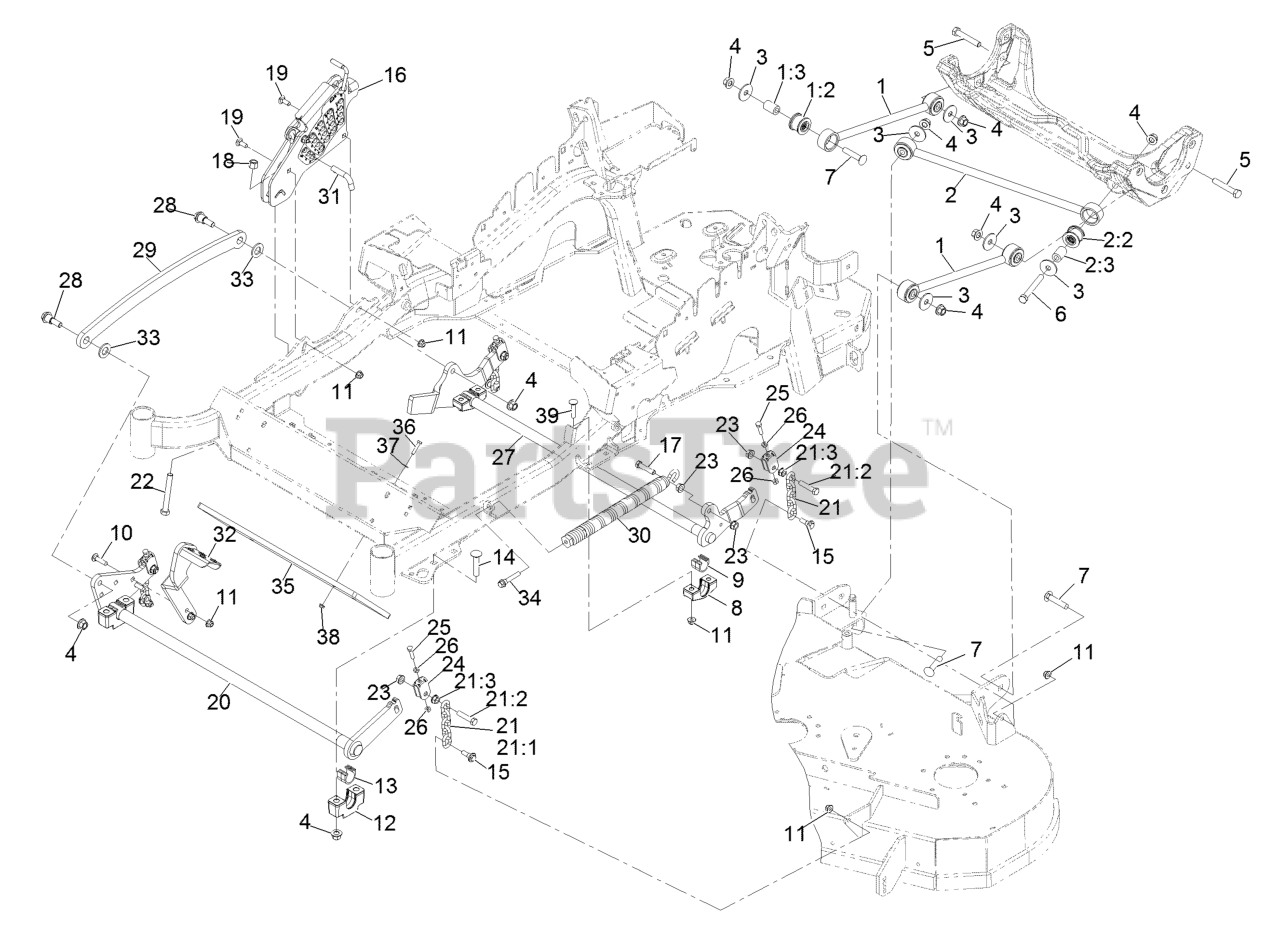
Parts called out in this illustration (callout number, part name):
1	DECK STRUT ASM
1:2	BUSHING-SUSPENSION, RUBBER
2	PANHARD ROD ASM
2:2	BUSHING-SUSPENSION, RUBBER
3	WASHER-THRUST
4	Nut-Lock 1/2-13
5	SCREW-HH
6	SCREW-HH
7	SCREW-CARR
9	BEARING-CROSS SHAFT, REAR
10	SCREW-CARR
11	NUT-HF, NI
12	SUPPORT-CROSS SHAFT, BEARING
13	BEARING-CROSS SHAFT, FRON
14	Bolt-Carriage 1/2-13 X 2 1/2 Spl Neck
15	SCREW-SHOULDER, HHF
16	HOC ASM
17	SCREW-HH
18	NUT-LOCK, NI
19	BOLT-CARR
20	DECKLIFT-FRONT
21	DECK LIFT CHAIN ASM
21:1	CHAIN-LIFT, DECK
21:2	SCREW-HH
22	BOLT-TAP
24	YOKE-ADJUST, DECK
25	SCREW-HH
26	NUT-JAM
27	LIFT-DECK, REAR
28	SCREW-SHOULDER, HHF 1/2-13 X 1.12
29	LINK-LIFT, DECK
30	SPRING-EXTENSION
31	PIN-HOC
32	LEVER-FOOT
33	WASHER-FLAT
34	BOLT-SHOULDER
35	WEIGHT,TOE BOARD
36	SCREW-HH
37	WASHER-FLAT
39	SCREW-CARR
